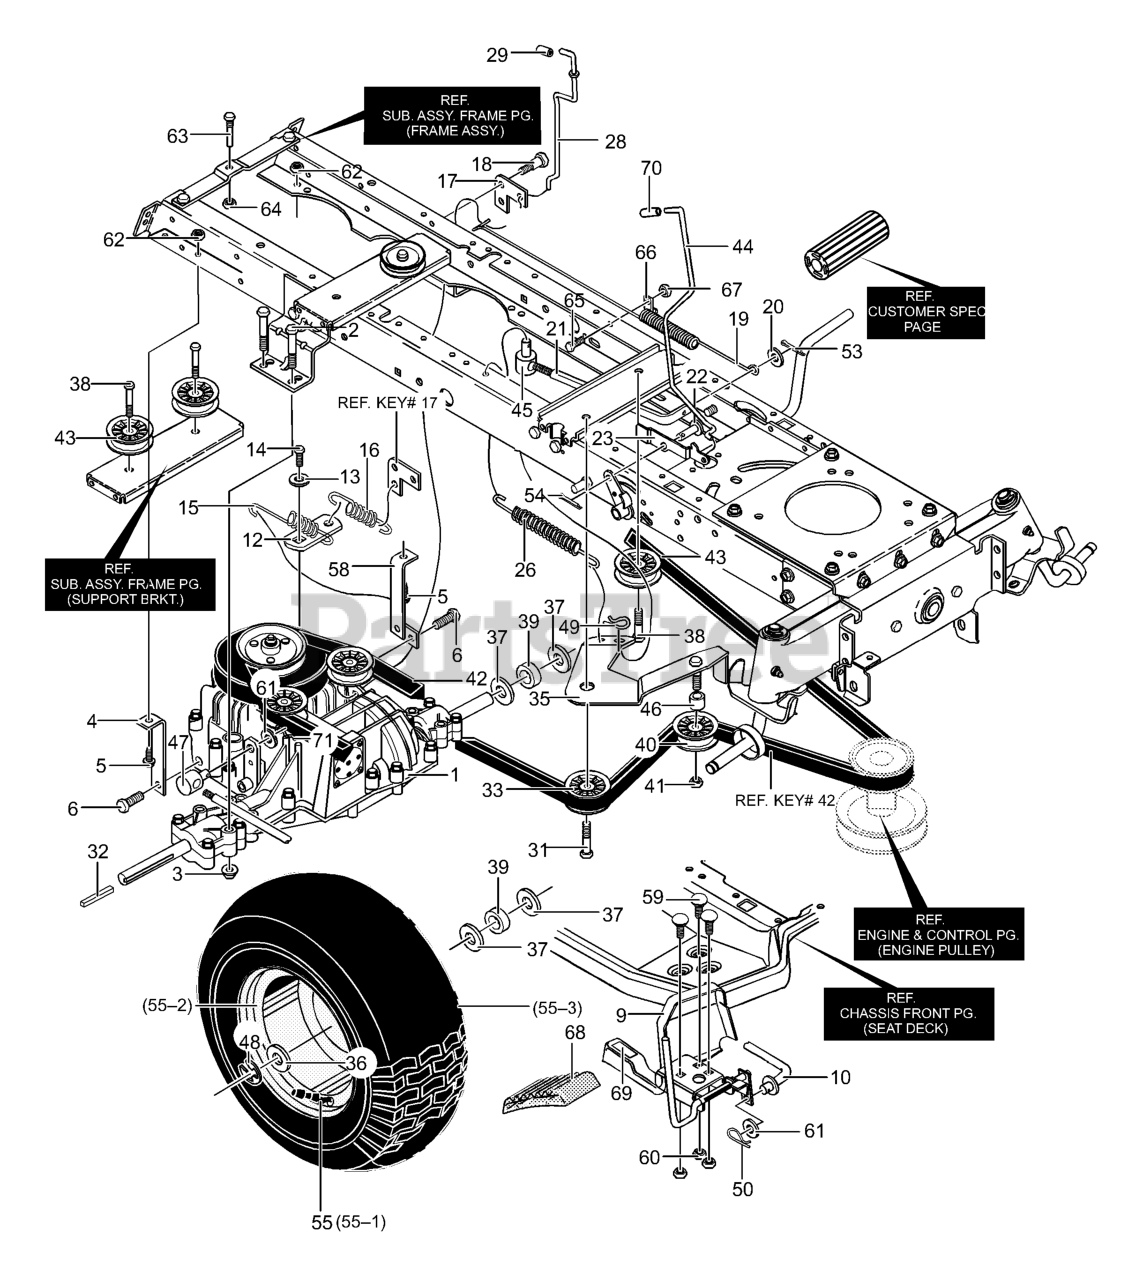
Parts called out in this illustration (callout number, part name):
1	Transaxle, MST205 **
2	Screw, 5/16-18 x 2.50
3	Nut, 5/16-18
4	Bracket, Stabilizer Hydro
5	Screw, 5/16-18 x 1.00
6	Screw, 5/16-18 x 0.75
9	Pedal Assy. Hydro
10	Rod, Foot Control
12	Bracket, Shift
13	Washer, Transaxle
14	Screw, 1/4-28x.750
15	Spring - Transaxle
17	Bracket, Disconnect Lever
18	Bolt, 5/16-18 HHSH
19	Spring, Brake
20	Washer, Flat
21	Rod, Clutch
22	Pin, Clevis
23	Latch, Park Brake
26	Spring, Tension
28	Rod, Disconnect
29	Grip, Hydro Disconnect
31	Screw, 3/8-16 x 1.25
32	Key, Square
33	Pulley, Idler
35	Assy, Idler Arm Traction
36	Washer, Flat
37	Washer, Flat
38	Screw, 3/8-16 x 1.25
40	Pulley, Idler
41	Nut, 3/8-16
42	Belt, V 4L 112.75
43	Pulley, Idler
44	Park Brake control Rod
45	Nut, 5/16-18 Adjusting
46	Spacer, 1/2 to 17mm
47	Adjusting Nut, 1/2-13
48	E-Ring
49	Pin, Hair
50	Pin, Hair
53	Pin, Cotter
54	Pin, Cotter
55	Tire & Rim
55-1	Valve Stem
58	Asm., Weld Bracket, Stabilizer
59	Bolt, Carriage 5/16-18x.75
60	Nut, 5/16-18 Hexwdfllk Whiz
61	Flatwasher, .515x.88x.0
62	Nut, 5/16-18 Hexwdfllk
63	Screw Guide
64	Nut, 5/16-18 Hexwdfllk Whiz
65	Screw, 1/4-20x.50
66	Retainer, Wire
67	Nut, 1/4-20 Wdflwhiz-Lk
68	Pedal, Pad Sandpaper
69	Pad, Toe Sandpaper
70	Cap, Dump Valve Rod
71	Hair Pin
